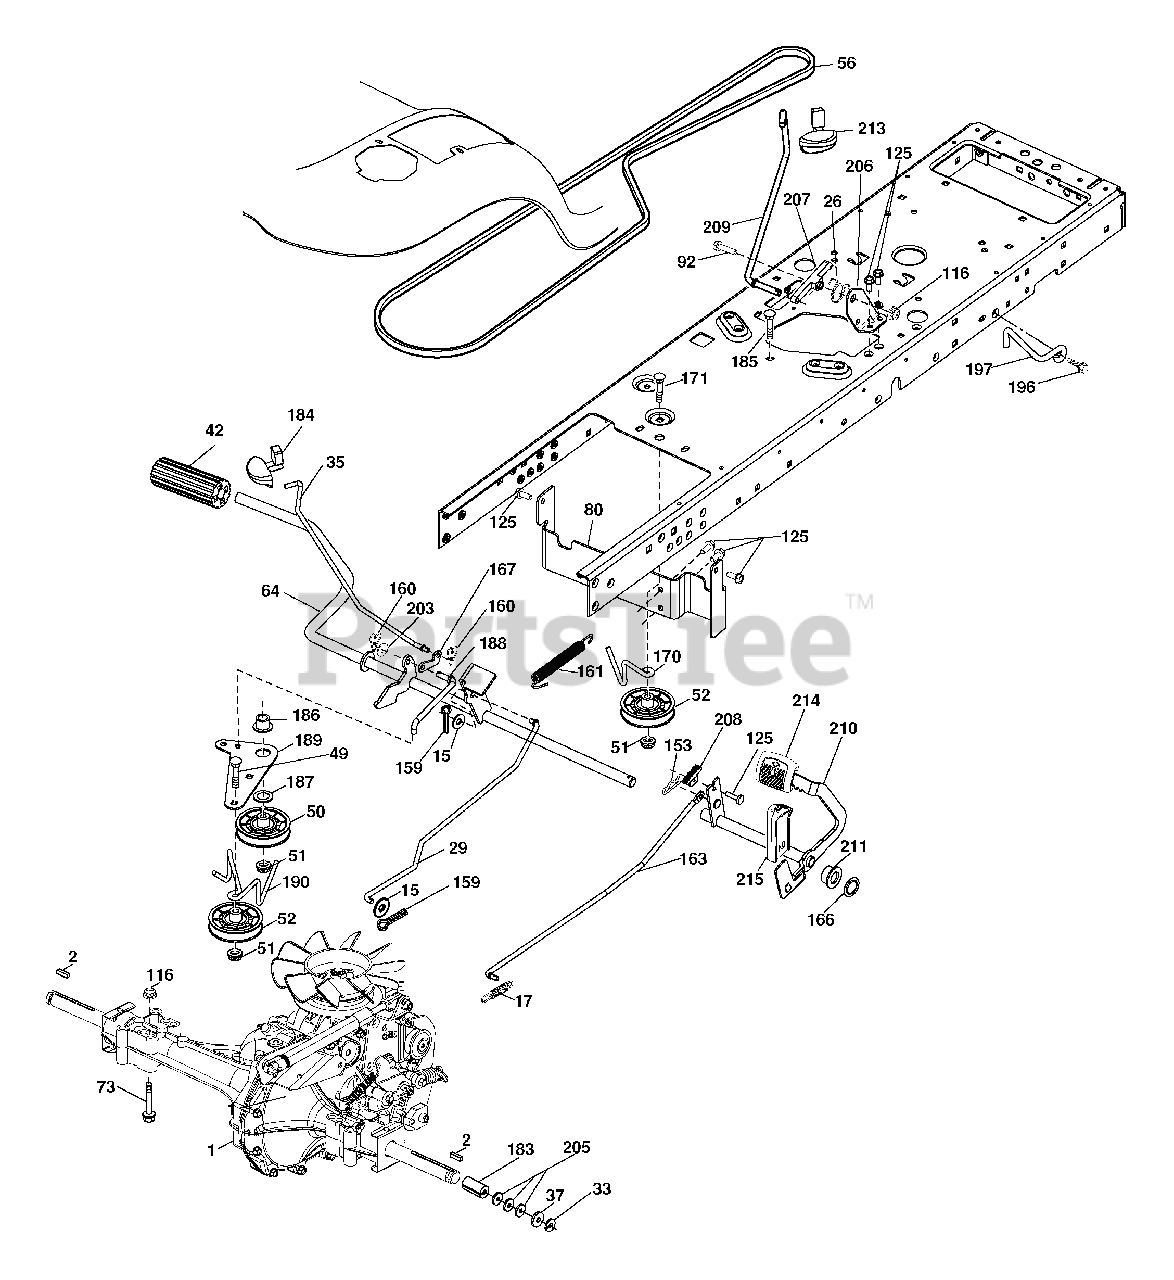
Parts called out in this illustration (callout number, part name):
2	Key
15	Washer 13/32 x 13/16 x 16 Ga.
17	Spring, Brake
26	Spring Return Cruise
29	Rod, Brake
33	Ring E
35	Rod, Brake, Park
37	Washer 25/32 x 1-1/4 x 16 Ga.
42	Cover, Foot Pedal
49	Bolt
50	Pulley Idler Flat
51	Lock Nut 3/8-16
52	Idler V-Groove 910" Offset
56	V-Belt, Drive
64	Shaft Asm. Pedal Brake Control
73	Bolt Hex Flghd 5/16-18 Gr. 5
80	Bracket Strap Torque
92	Bolt Fin Hex 5/16-18 unc x 1.25
116	Nut Lock Hex Flange 5/16-18
125	Screw 5/16-18 x 3/4
153	Retainer Spring
159	Pin Cotter 1/8 x 3/4
160	Retainer Clip
161	Spring, Return, Clutch
163	Rod Pedal Control
166	Nut Push .625
167	Latch Brake Parking
170	Keeper Belt Centerspan
171	Bolt
183	Spacer Axle
184	Handle Parking Brake
185	Bolt
186	Spacer Retainer
187	Washer
188	Link Clutch Ground Drive
189	Bellcrank Ground Drive
190	Keeper Bellcrank Ground Drive
196	Screw 3/8-16 x 1
197	Link Clutch Anti Rotation
203	Washer 11/32 x 11/16 x 16 Ga.
205	Washer 25/32 x 1-5/8 x 16 Ga.
206	Bracket Mount Latch Cruise
207	Latch Control Cruise
208	Gear Sector Control Cruise
209	Rod Control Cruise
210	Rockr Asm. Pdeal Control
211	Bearing Nylon
213	Knob control Cruise
214	Pad Pedal Forward
215	Pad Pedal Reverse
